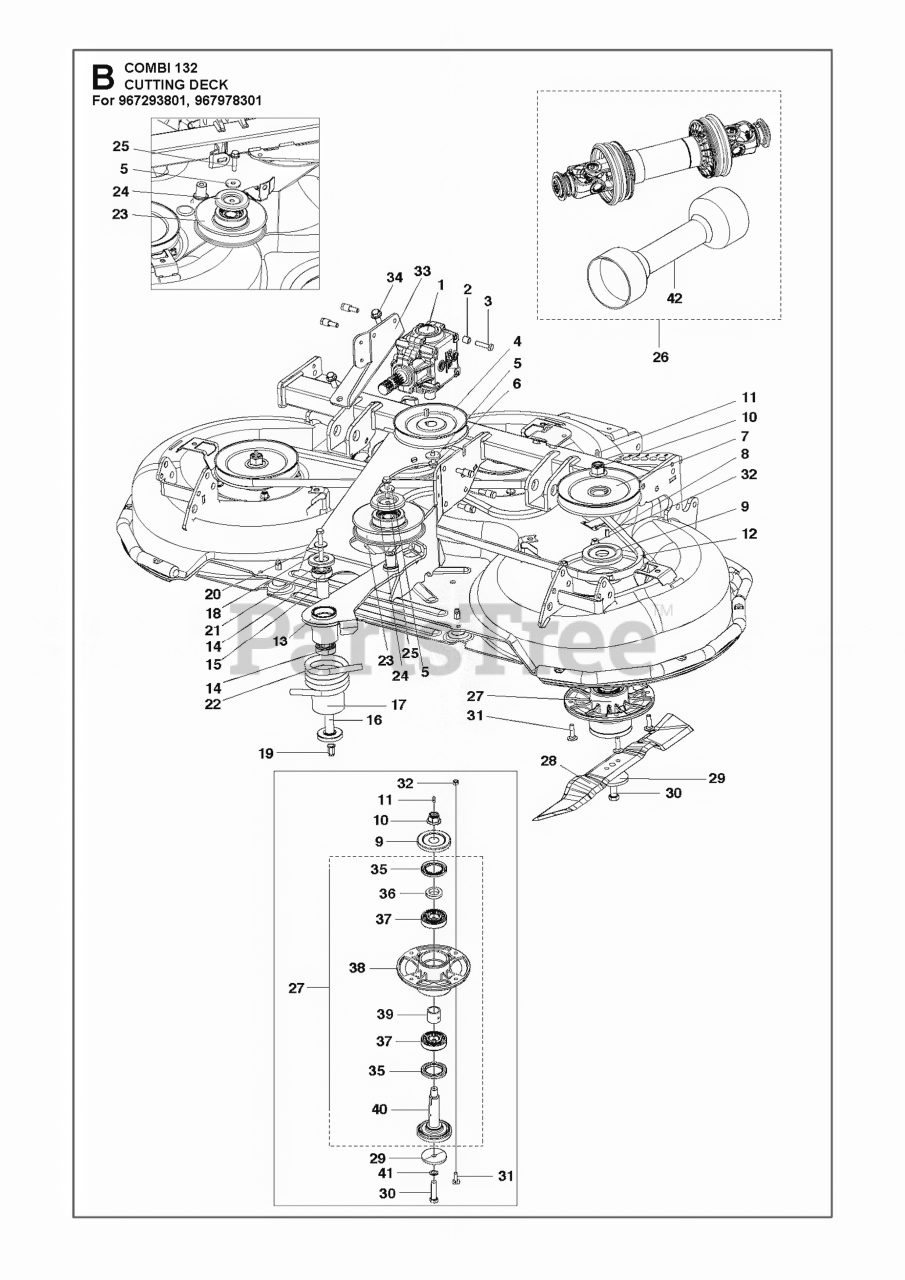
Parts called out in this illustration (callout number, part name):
11	GREASE NIPPLE
14	BALL BEARING
17	SPACER, IDLER PIVOT
19	BLIND RIVET NUT
21	DUST SHIELD
25	SCREW EHHFM
28	BLADE REAR DISCHARGE/MULCH C13
32	NUT FLANGE
37	BALL BEARING 6305 C3
